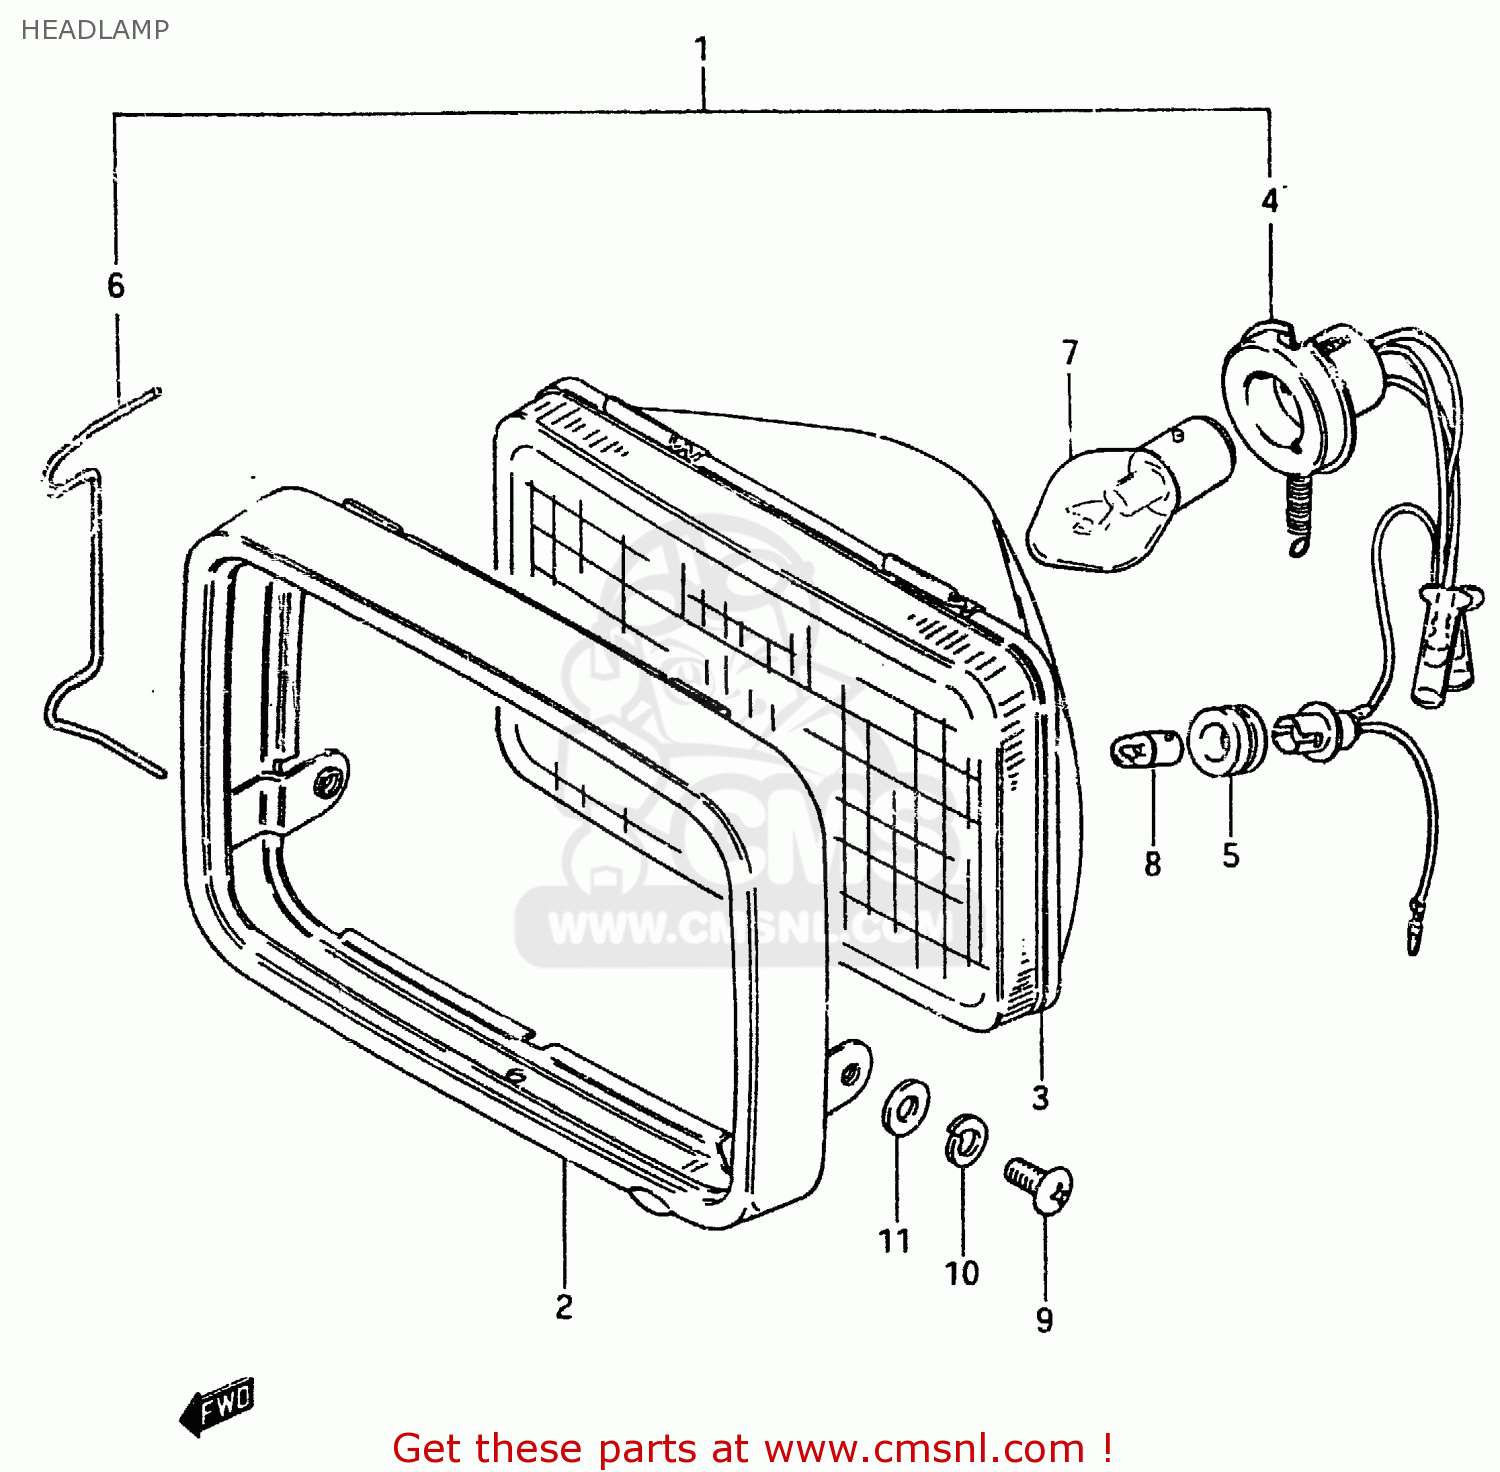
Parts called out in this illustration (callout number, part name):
1	HEADLAMP ASSY
2	RIM
3	UNIT
4	SOCKET
5	JOINT,RUBBER
6	SPRING
7	BULB (6V,25/25W)
8	BULB (6V,4W)
9	SCREW
10	LOCK WASHER
11	WASHER
